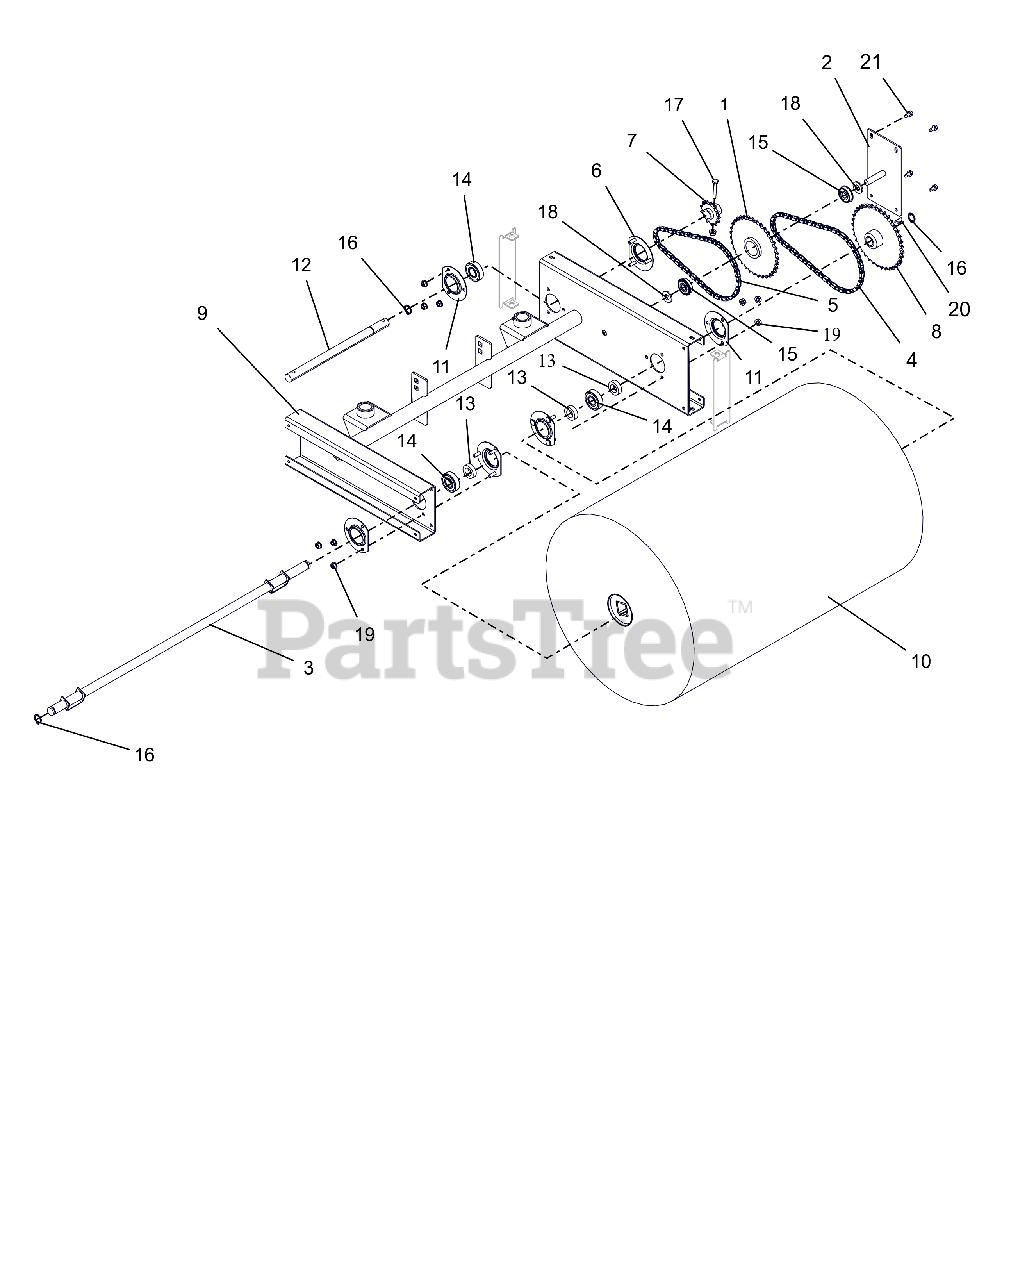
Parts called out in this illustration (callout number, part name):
1	SPROCKET, REDUCTION IDLER
2	PLATE, IDLER REDUCTION MOUNT
3	SHAFT, 28" BRUSH
4	CHAIN, #40-54 LINKS
5	CHAIN, #41-50 LINKS
6	BEARING FLANGE
7	SPROCKET, DRIVE
8	SPROCKET, DRIVEN
9	FRAME, POWER BROOM-DELUXE
10	BRUSH, 18"DIA X 28"WIDE
11	BEARING FLANGE
12	SHAFT, TRANSMISSION
13	SPACER .755X1.250X.370
14	BRG-BALL .750X1.750X.50
15	BRG-BALL .50X1.38X.438 SEALED
16	RG-RTNG-EXT .689X.078
17	@BLT-HEX .25-20X1.75 GR5 YWZC
18	WSHR-FL-STL .536X1.07X.109 YZ
19	@NUT-LK-TOP-FLG .25-20 YWZC
20	KEY-WDRF .188X.75X.313 SAE 9
21	SCR-TAP .25-20X.50 HWH TR YWZ
